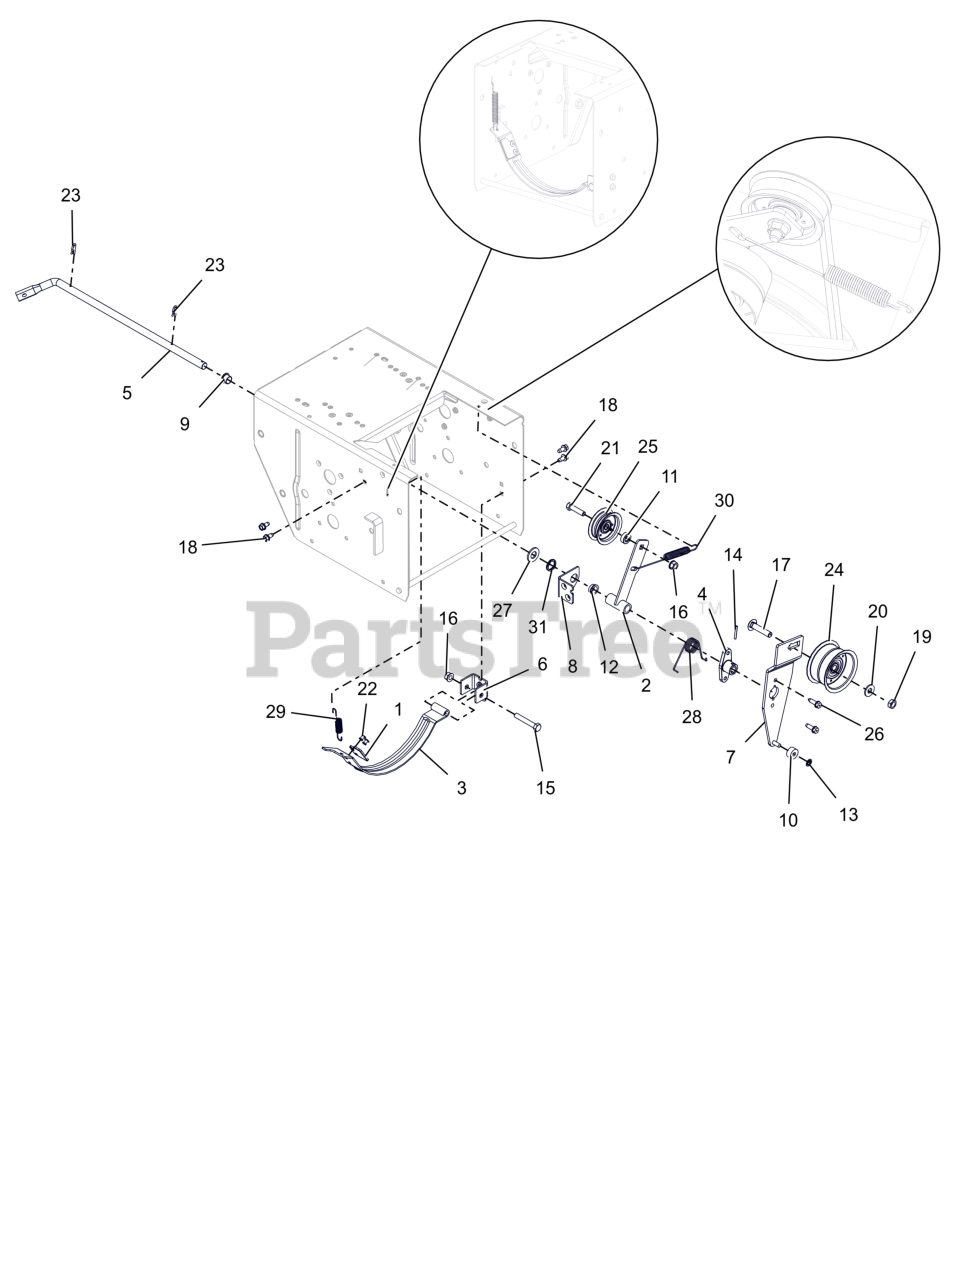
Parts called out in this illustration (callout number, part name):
1	PAD, BRAKE
2	ARM, IDLER-TRACTION
3	ARM, BRAKE-ATTACHMENT
4	HUB, BRAKE ARM
5	ARM, ATTACHMENT
6	PIVOT, BRAKE
7	ARM, IDLER - ATTACHMENT
8	BRACKET, SUPPORT
9	BUSHING, POLYLINER-.50 SPLIT
10	BSHG,SLV .265 X .625 X .375
11	SPCR, BRG .315X.500X.358X.281
12	BSHG,FLANGE .500X.625X.270X.75
13	RG-RTNG-EXT .250X.010
14	PIN-ROLL .125X1.00
15	BLT, HEX .31-18X2.00 G5 ZCC
16	NUT-LK-TOP-FLG .312-18 GF ZCC
17	BLT, RHSSN .38-16X1.75 G5 ZCC
18	SCR-TAP .25-20X.50 HWH ZCC
19	NUT-LK-CTR-JAM .375-16 GB ZCC
20	WSHR,FLT .375X.875X.083 ZCC
21	BLT, HEX .31-18X1.25 G5 ZCC
22	RVT, POP .1875 ZCC
23	CLIP, SPRING
24	IDLER, FLANGE -2.75 OD X .375 ID
25	IDLER, FLAT - 2.00"
26	SCR,TAP .25-20X.75 HWH TR ZCC
27	WSHR,FLT .531X1.062X.095 ZCC
28	SG-TORS .067X.88
29	SPRING-EXT .437 X .438 X 2.64
30	SG-TENS .06X.482X5.35
31	WAVE SPRING .600X.875X.25FH
